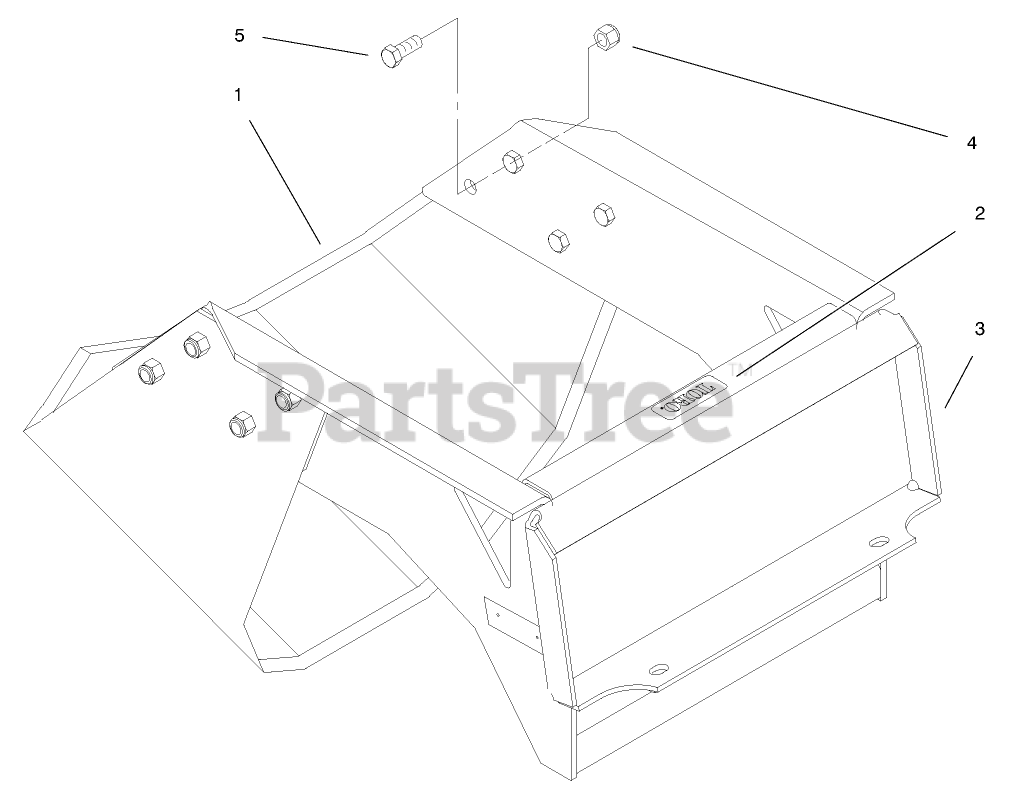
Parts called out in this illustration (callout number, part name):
1	PLATE - BLADE
2	DECAL-ATTACHMENT, DINGO
3	WA - BLADE MOUNT
4	NUT-HEX
5	SCREW-HH
